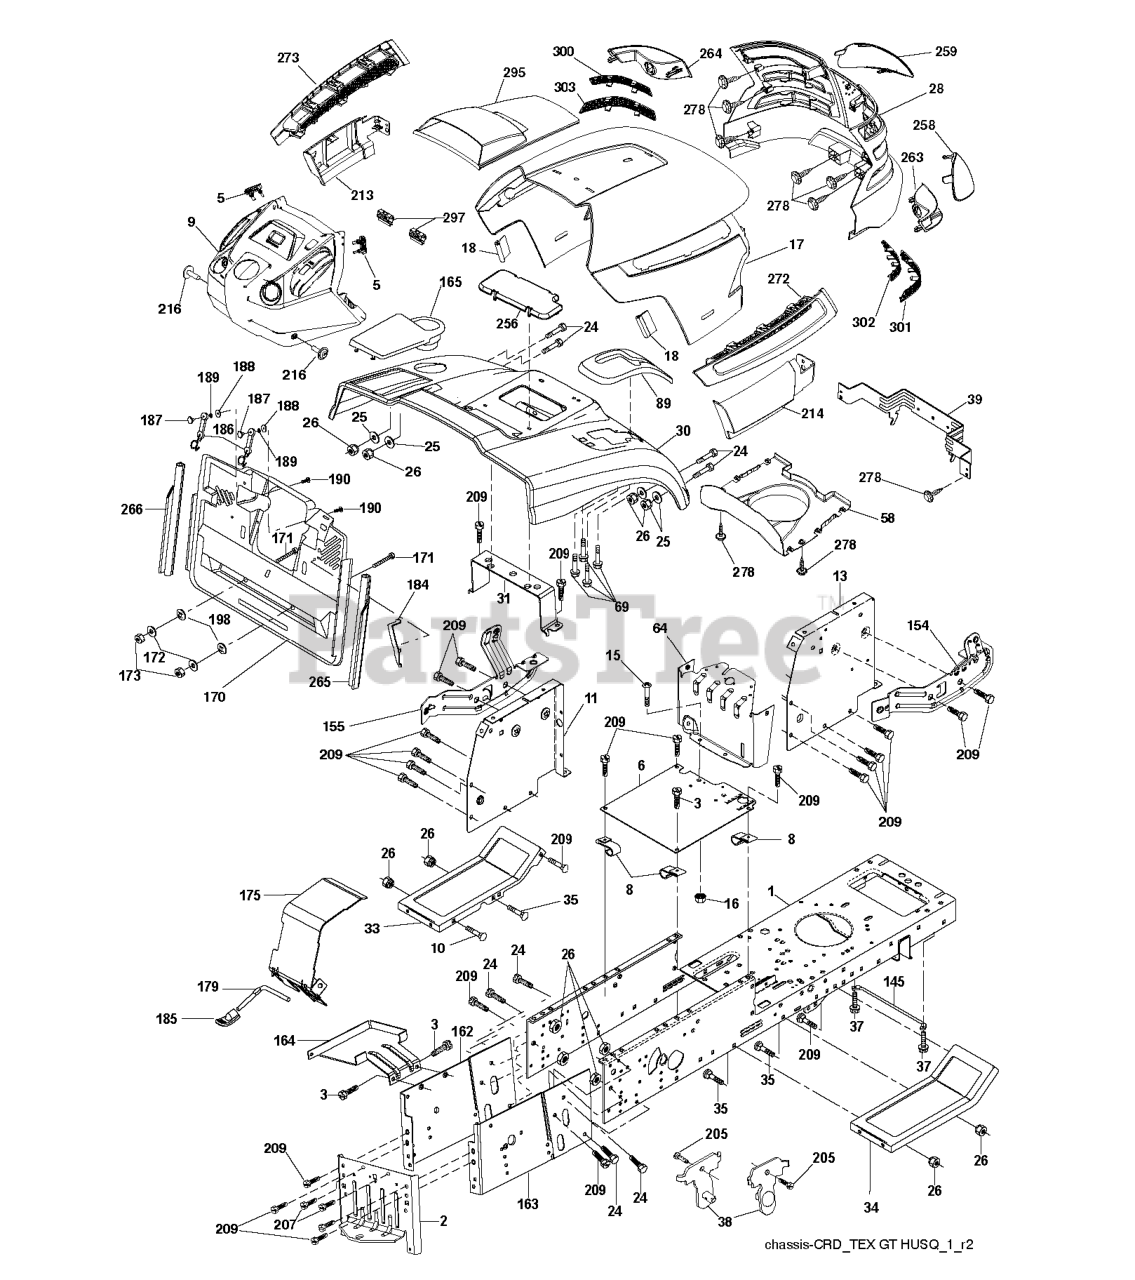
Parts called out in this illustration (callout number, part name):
2	DRAWBAR
3	SCREW 3/8-16X3/4
5	BUMPER DASH
6	PLATE
8	CLIP,INSULATOR
10	BOLT D
11	PANEL DASH LH
13	PANEL DASH RH
15	Screw, Machine, Truss Head 5/16-18 UNC x 3/4
16	NUT
17	HOOD
18	BUMPER.HOOD.TEX.HUSQVARNA
25	WASHER
26	NUT
28	GRILL.ASM.HUSQ.TG/CRD.W/TRIM
30	CONSOLE.CRD.AUTO.GRY
31	BRACKET SUPPORT FENDER
33	FOOTREST PNT LH
34	FOOTREST PNT RH
37	Screw 5/16-18 x 1/2 Hex, Self Tapping 5/16-18 x 1/2
38	BRACKET ASM PIVOT MOWER REAR
39	HOOD PIVOT BRACKET
58	AIR.DUCT.TEXGT.HUSQ.31
69	SCREW.HI-LO.CONSOLE
89	CONSOLE.CRD.AUTO.GREY.2005
145	ROD.PIVOT.HOOD
162	BRACKET
163	BRACKET EXTEN CHASSIS RH CRD
165	COVER.BATTERY.BGGR.ELE
172	WASHER
175	DOOR TRAP
179	ROD PIVOT FBI
184	BRACKET.ACTUATOR.BAGGER.SRD
186	LATCH ASSY
187	WELDNUT
189	LOCKWASHER #10
190	SCREW
207	SCREW, 5/16-18 X 1/2
209	SCREW, 3/8-16X3/4
213	SKIRT.HOOD.SIDE.HUSQ.LH.GREY
214	SKIRT.HOOD.SIDE.HUSQ.RH.GREY
216	SCREW 14-20 X 5/8
256	COVER FENDER CRD
258	LENS.RH.TEX.GT.HUSQ.CL
259	LENS.LH.TEX.GT.HUSQ.CL
263	BEZEL.RH.TEX.GT.HUSQ
264	BEZEL.LH.TEX.GT.HUSQ
265	SEALING
266	SEALING
272	VENT.SIDE.HOOD.HUSQ.RH.GREY
273	VENT.SIDE.HOOD.HUSQ.LH.GRAY
278	SCREW.#10 X 0.750.BOS
295	HOOD VENT
300	INSERT.HEX.GRILL.HUSQ.
301	INSERT.HEX.GRILL.HUSQ.GREY
302	INSERT.HEX.GRILL.HUSQ.
303	INSERT.HEX.GRILL.HUSQ.
